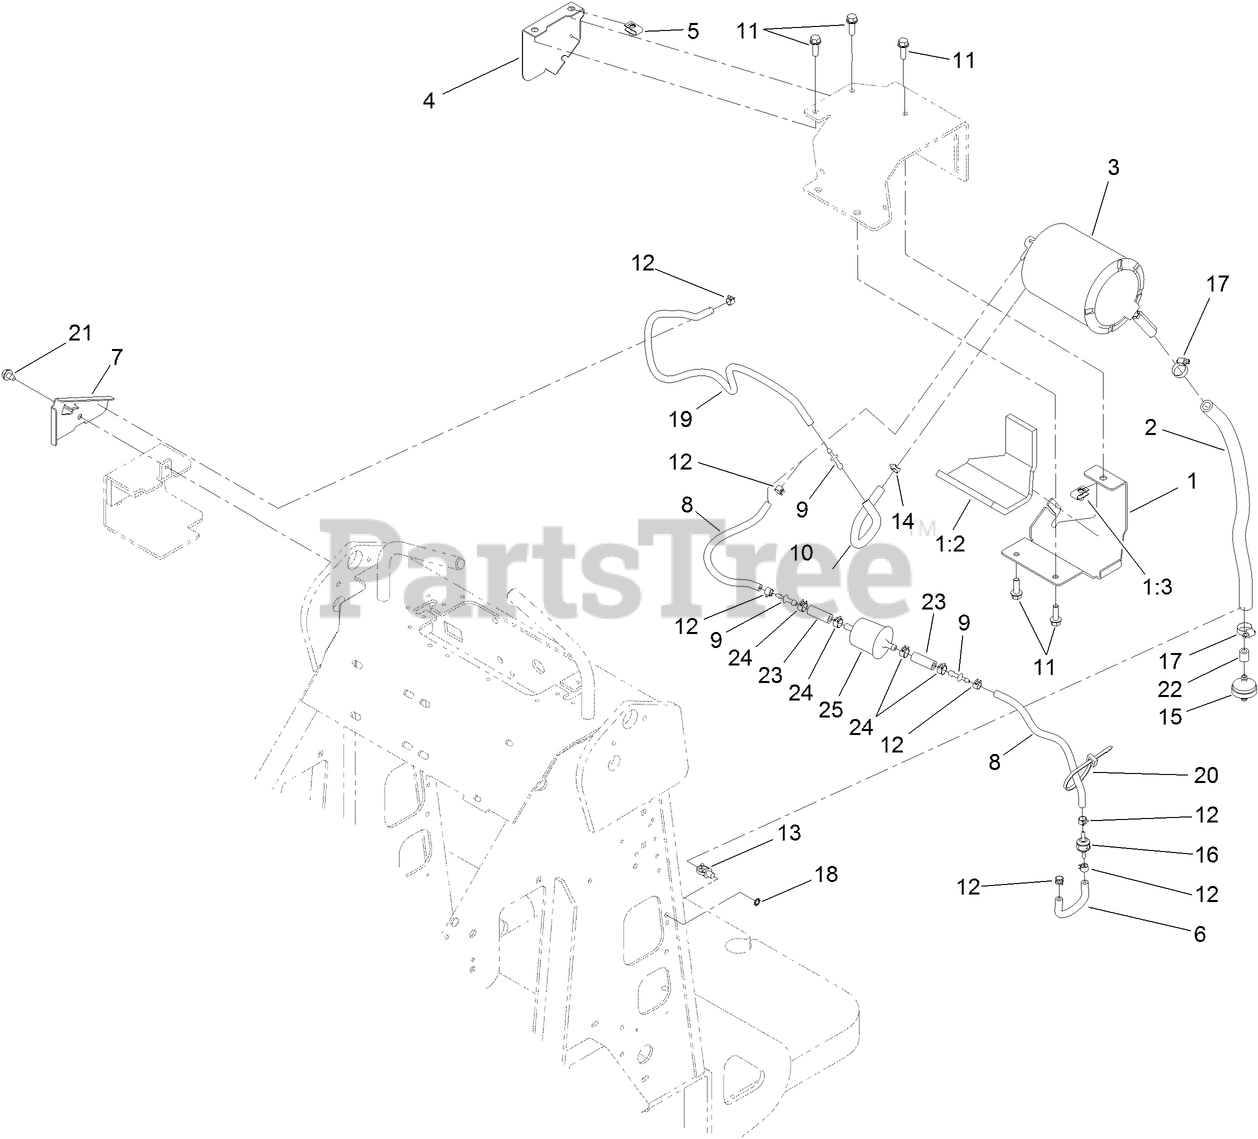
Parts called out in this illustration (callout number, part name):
1	CANISTER MOUNT ASM
1:2	PAD-FOAM
1:3	NUT-CLIP, U
2	HOSE-VENT
3	CANISTER-CARBON, 1200CC
4	COVER-CANISTER
5	NUT-CLIP, U
6	HOSE-FUEL
7	PLATE-HOSE RETAINER, RH
8	HOSE-FUEL
9	FITTING-STRAIGHT
10	HOSE-FUEL
11	SCREW-HHF
12	CLAMP-HOSE
13	CLIP-TIE
14	CLAMP-HOSE
15	FILTER-FUEL, INLINE
17	CLAMP-HOSE
18	WASHER-LOCK
19	HOSE-FUEL
20	TIE-CABLE
21	SCREW
22	HOSE-FUEL
23	HOSE-FUEL
24	CLAMP-HOSE
25	FILTER-FUEL
